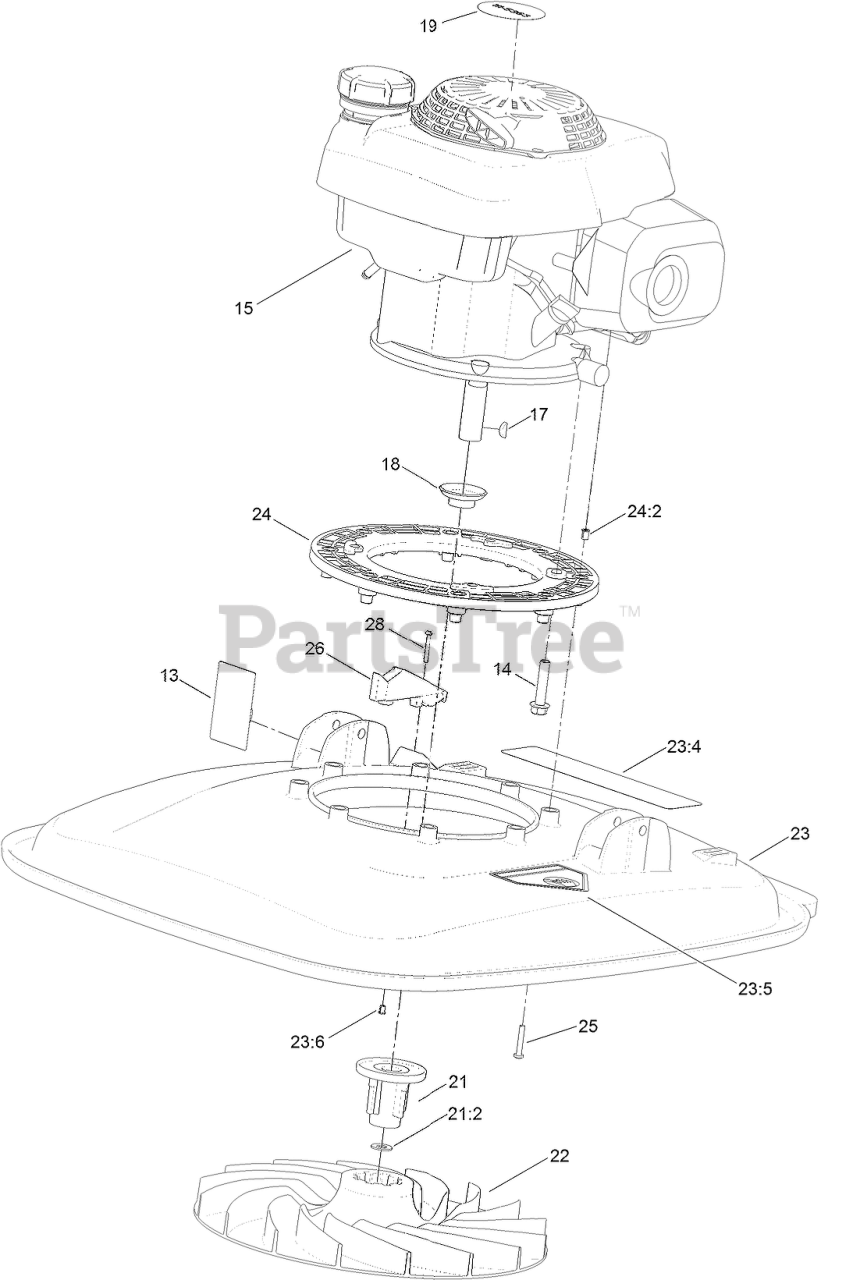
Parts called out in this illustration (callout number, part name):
13	DECAL
14	SCREW-TAPTITE
15	ENGINE-HONDA
17	KEY-WOODRUFF
18	PROTECTOR-SEAL, OIL
19	DECAL-ENGINE
21	DRIVE AND SPACER ASM
21:2	WASHER-PLAIN
22	IMPELLER
23	DECK ASM
23:4	DECAL-WARNING
23:5	DECAL-DANGER
23:6	INSERT
24	FRAME-ENGINE
24:2	INSERT-BRASS
25	SET-SCREW
26	BRACKET
28	SCREW
